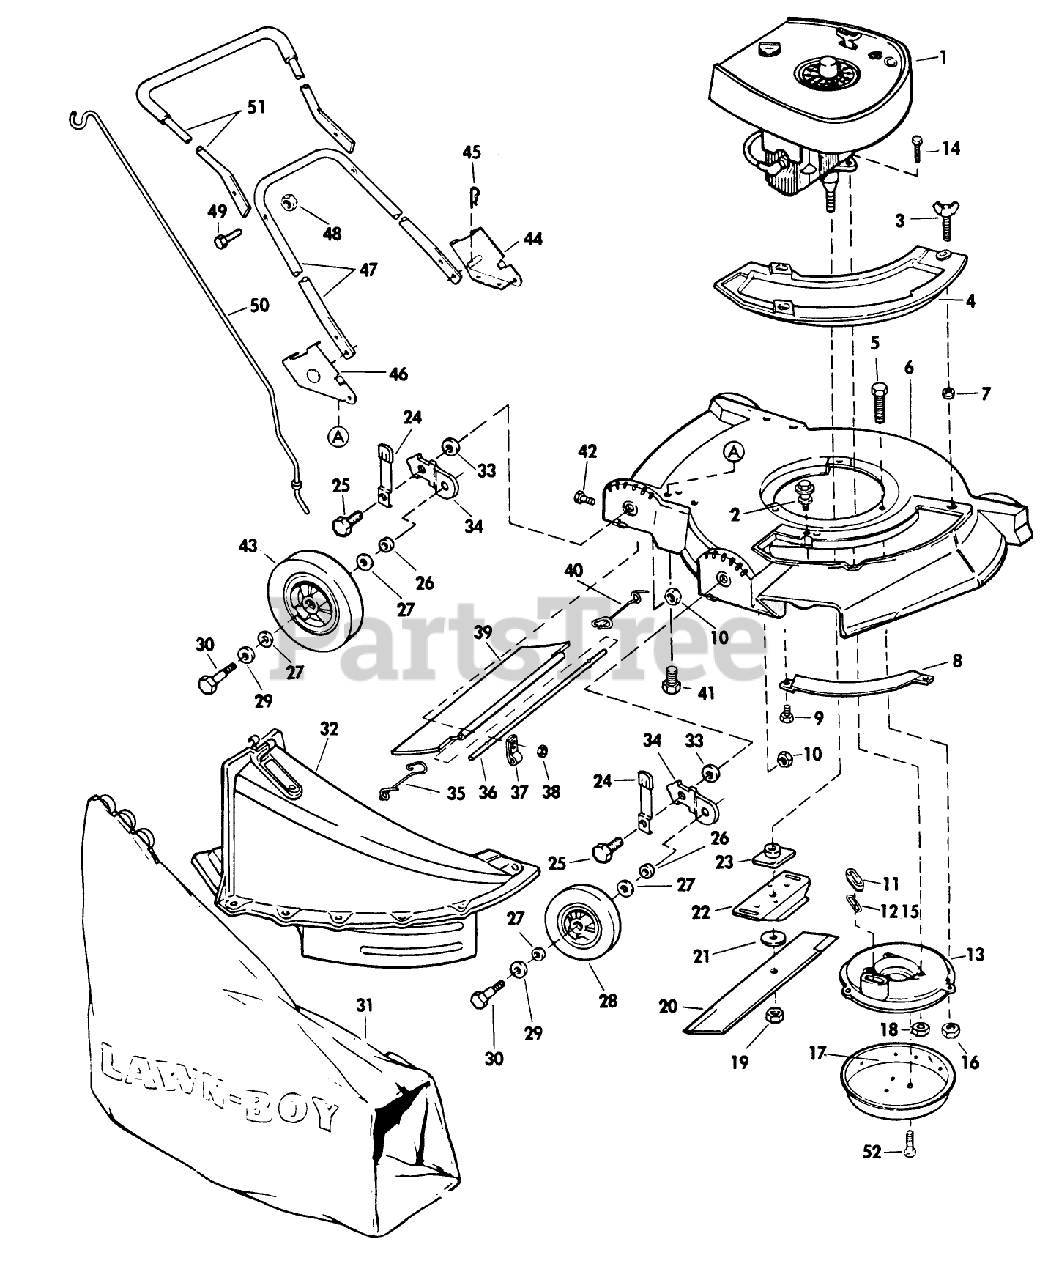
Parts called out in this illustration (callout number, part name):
1	See Note #2 at bottom of this page.
3	WING SCREW LAWRE
5	SCREW V
8	TOE BAR 19"
8	BAR-TOE
10	LOCKNUT
12	GASKET S
15	GASKET S
16	NUT-LOCK F
18	NUT-LOCK F
19	NUT-BLADE
21	WASHER
23	PLATE AND COLLAR ASM
26	WASHER WROUGHT
28	WHEEL & TIRE KIT
30	BOLT WHEEL
31	89802 LB WHOLE GOODS
35	SPRING;TRAILING SHIELD RH
36	ROD T/SHIELD ADV WIRE
36	ROD 21" ADVANCE
37	CLAMP ROD KMC
38	LOCKNUT E
40	SPRIG T/SHLD ASOC
45	HAIR PIN
48	LOCKNUT E
50	ROD GRASSBAG
